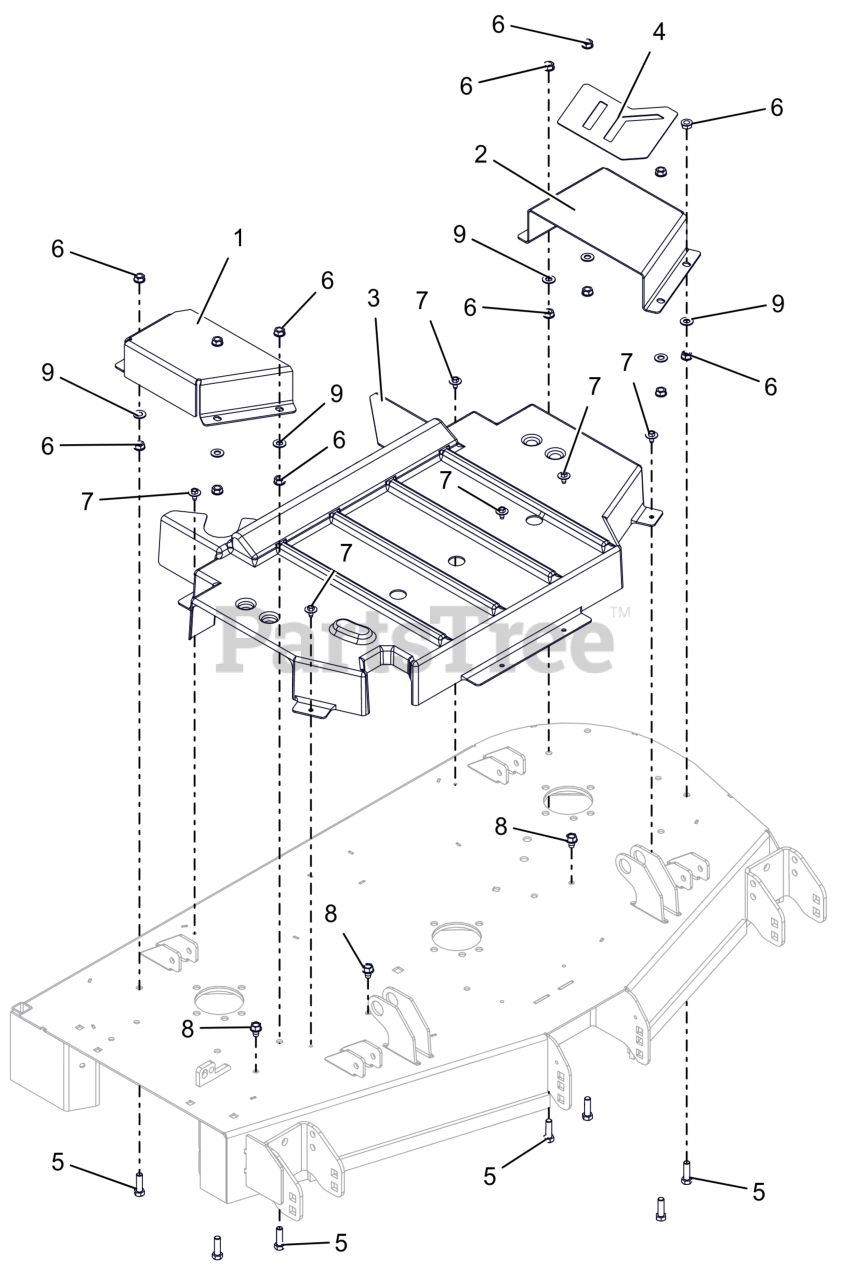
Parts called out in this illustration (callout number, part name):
1	GUARD BELT, 48" RIGHT CE
2	GUARD BELT 48" LEFT CE
3	GUARD, CENTER DECK SPINDLE CE
4	GRIP TAPE 48 BELT COVER
5	BLT, HEX .38-16X1.25 G5 ZCC
6	NUT, SPNLK-FLG .38-16 G5 ZCC
7	SCR, TAP .25-20X.50 LG HWH ZCC
8	SCR,TAP .375-16X.50 HWH TR ZCC
9	WSHR,FLT .406X.812X.065 ZCC
